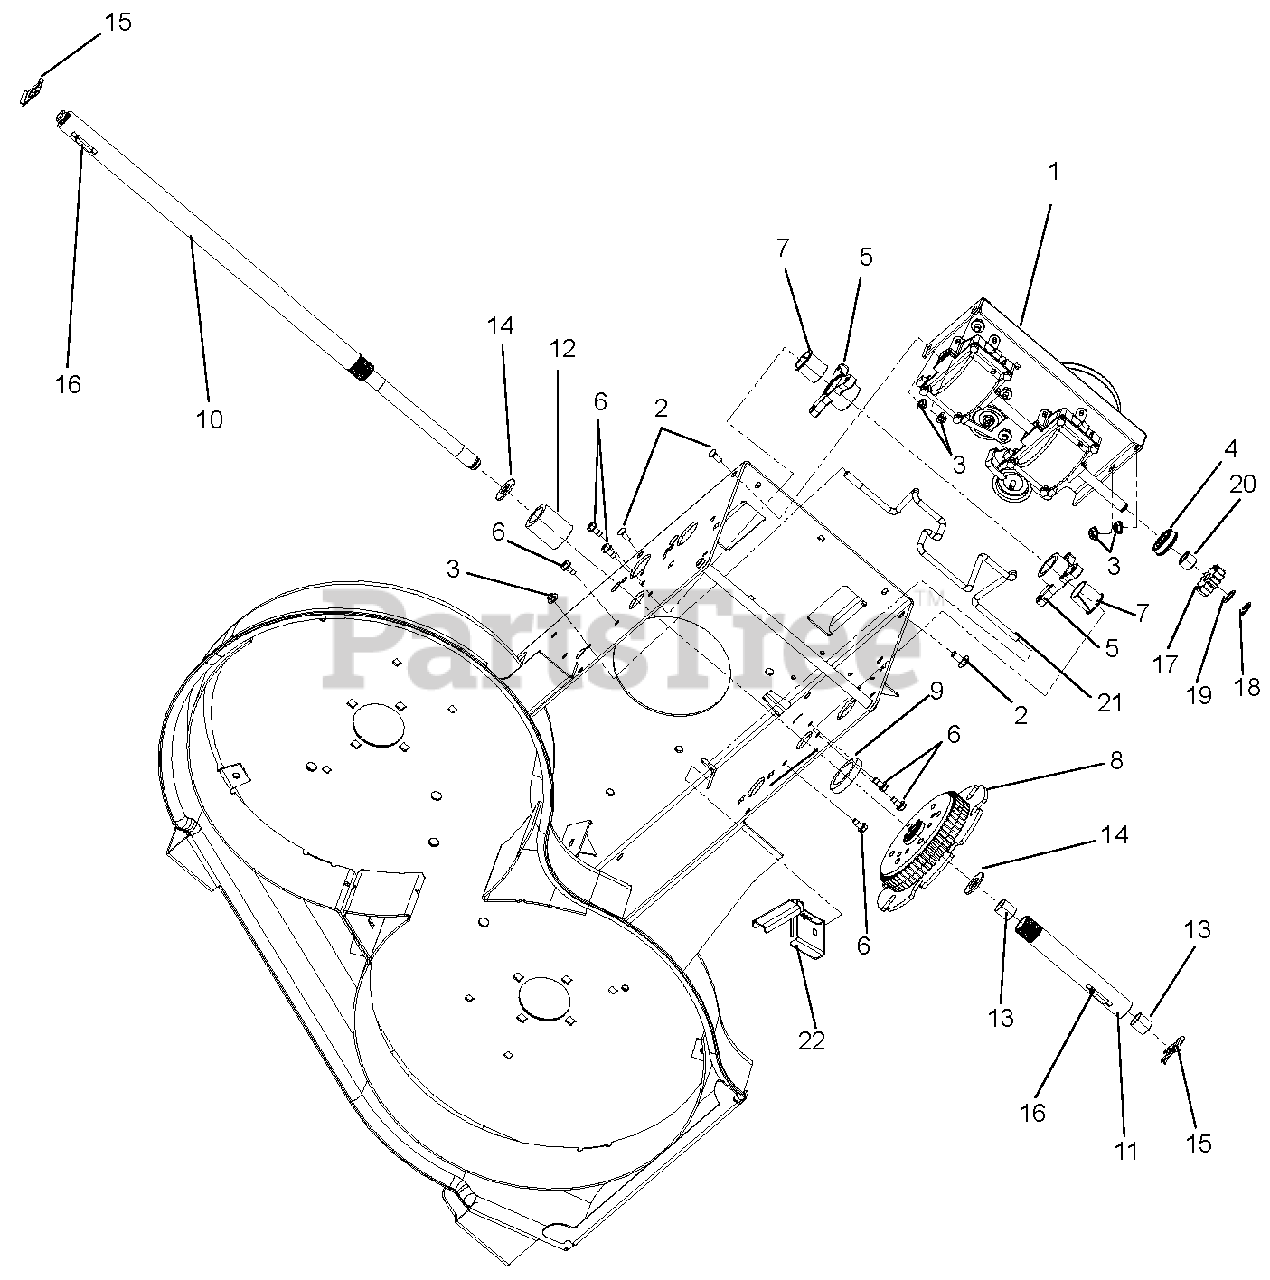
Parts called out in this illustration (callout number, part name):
1	Kit, WAW Transmission
2	Bolt, Round Head, Square Neck .31-18 x .75
3	Nut, Locking Top Flange .31-18
4	Bearing, Sealed Ball .50 1.38 x .438
5	Bushing, Rake Shaft 1"
6	Screw, Tapping Hex Washer Head .25-20 x .50
7	Bushing, Flange Split 1.0"
8	Kit, Differential
9	Washer, Flat Nylon 1.42 x 2.03 x .35
10	Shaft, Axle Long
11	Shaft, Axle Short
12	Spacer 1.0 x 1.5 x 1.57
13	Bushing, Sleeve .706 x .764 x .75
14	Washer, Flat Steel 1.0 x 1.50 x .062
15	Clip, Snap .625 Diameter
16	Key, Rectifier .25 x .188 x 1.00
17	Pinion, Transmission Drive
18	Ring, External Retaining .500 x .042
19	Washer, Thrust .500 x .020
20	Retainer, Bearing
21	Belt Finger
22	Guide, Vertical Belt
